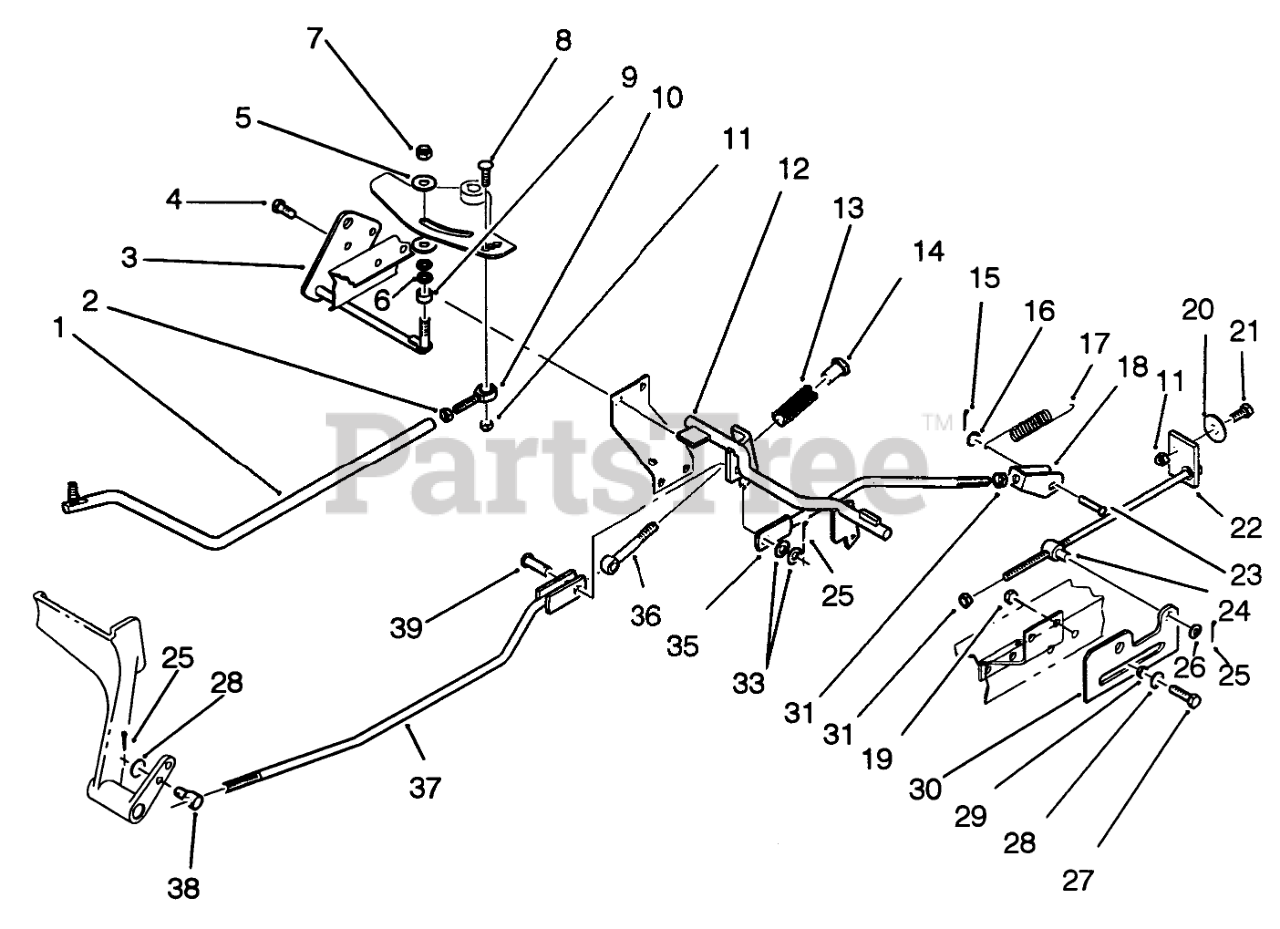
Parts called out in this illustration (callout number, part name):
1	ROD-CONTROL R
2	Nut
3	WLDMT-ROD R
4	Screw
5	FRICTION WASHER
6	WASHER-SPRING DISC
7	NUT
8	Bolt-Carriage
9	SPACER
10	BALL-END
11	NUT-LOCK, NI
12	WLDMT-NEUTRAL SHA R
13	SPRING-COMPRESSION
14	NUT-RETAINER
15	PIN-COTTER
16	WASHER-FLAT
17	SPRING-EXTENSION
18	WLDMT-CLEVIS
20	WASHER
21	SCREW-HH
22	WLDMT-BOLT
24	TRUNNION
25	PIN-COTTER
26	WASHER-PLAIN
27	SCREW-HH
28	WASHER-PLAIN
29	SPACER
30	PLATE R
31	NUT-JAM
33	Washer
34	Collar
35	WLDMT-ROD
36	EYE-BOLT
37	WLDMT-BRAKE ROD
38	TRUNNION
39	CLEVIS PIN
